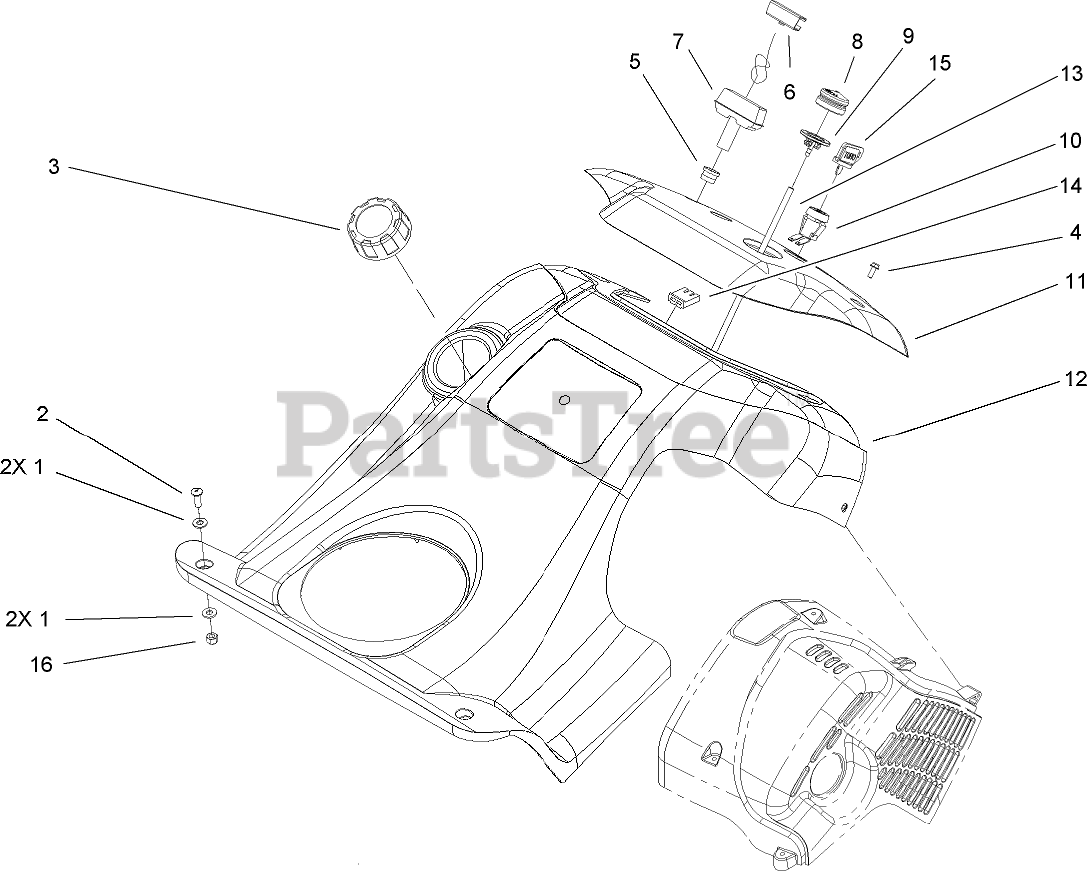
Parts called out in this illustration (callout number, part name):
1	WASHER-FLAT
2	SCREW-PPH
3	GAS CAP ASM
4	SCREW-HWH
5	GUIDE-ROPE, STARTER
6	CLIP-STARTER
7	HANDLE-START
8	BULB-PRIMER
9	BODY-PRIMER
10	SWITCH
11	PANEL-CONTROL
12	RECOIL UPPER SHROUD ASM
13	HOSE-PRIMER
14	CONNECTOR-BODY
15	KEY-IGNITION
16	NUT-LOCK, NI
